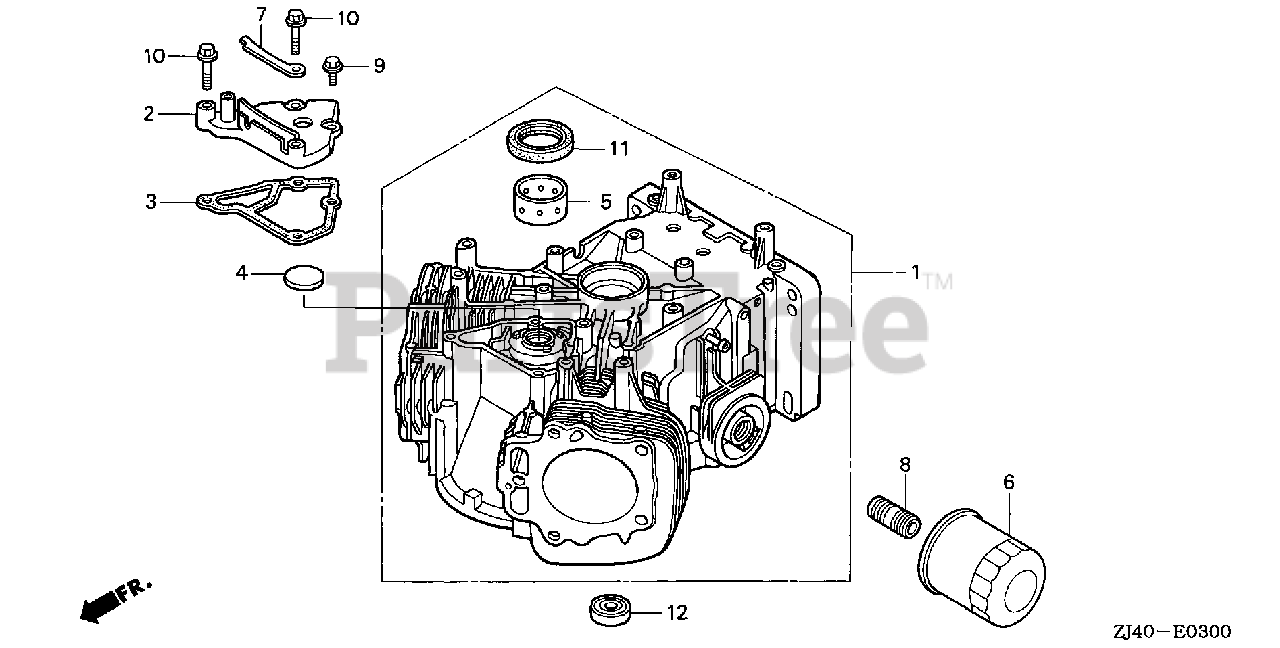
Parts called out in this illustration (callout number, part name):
1	CYLINDER ASSY. (W/O-PUMP)
2	COVER, BREATHER
3	GASKET, BREATHER COVER
4	VALVE, BREATHER
5	BEARING A, MAIN (BLUE) (TO SELECT CORRECT BEARING, SEE THE SERVICE MANUAL.)
5	BEARING B, MAIN (BLACK) (TO SELECT CORRECT BEARING, SEE THE SERVICE MANUAL.)
5	BEARING C, MAIN (BROWN) (TO SELECT CORRECT BEARING, SEE THE SERVICE MANUAL.)
6	FILTER, OIL (FILTECH TOYO ROKI) (SOLD INDIVIDUALLY)
6	FILTER, OIL (TOYO ROKI) (SOLD INDIVIDUALLY)
7	CLAMP, WIRE
8	HOLDER, OIL FILTER
9	BOLT, FLANGE (6X16) (CT200)
10	BOLT, FLANGE (6X32) (CT200)
11	OIL SEAL (38X58X11)
12	BEARING, RADIAL BALL (6003)
